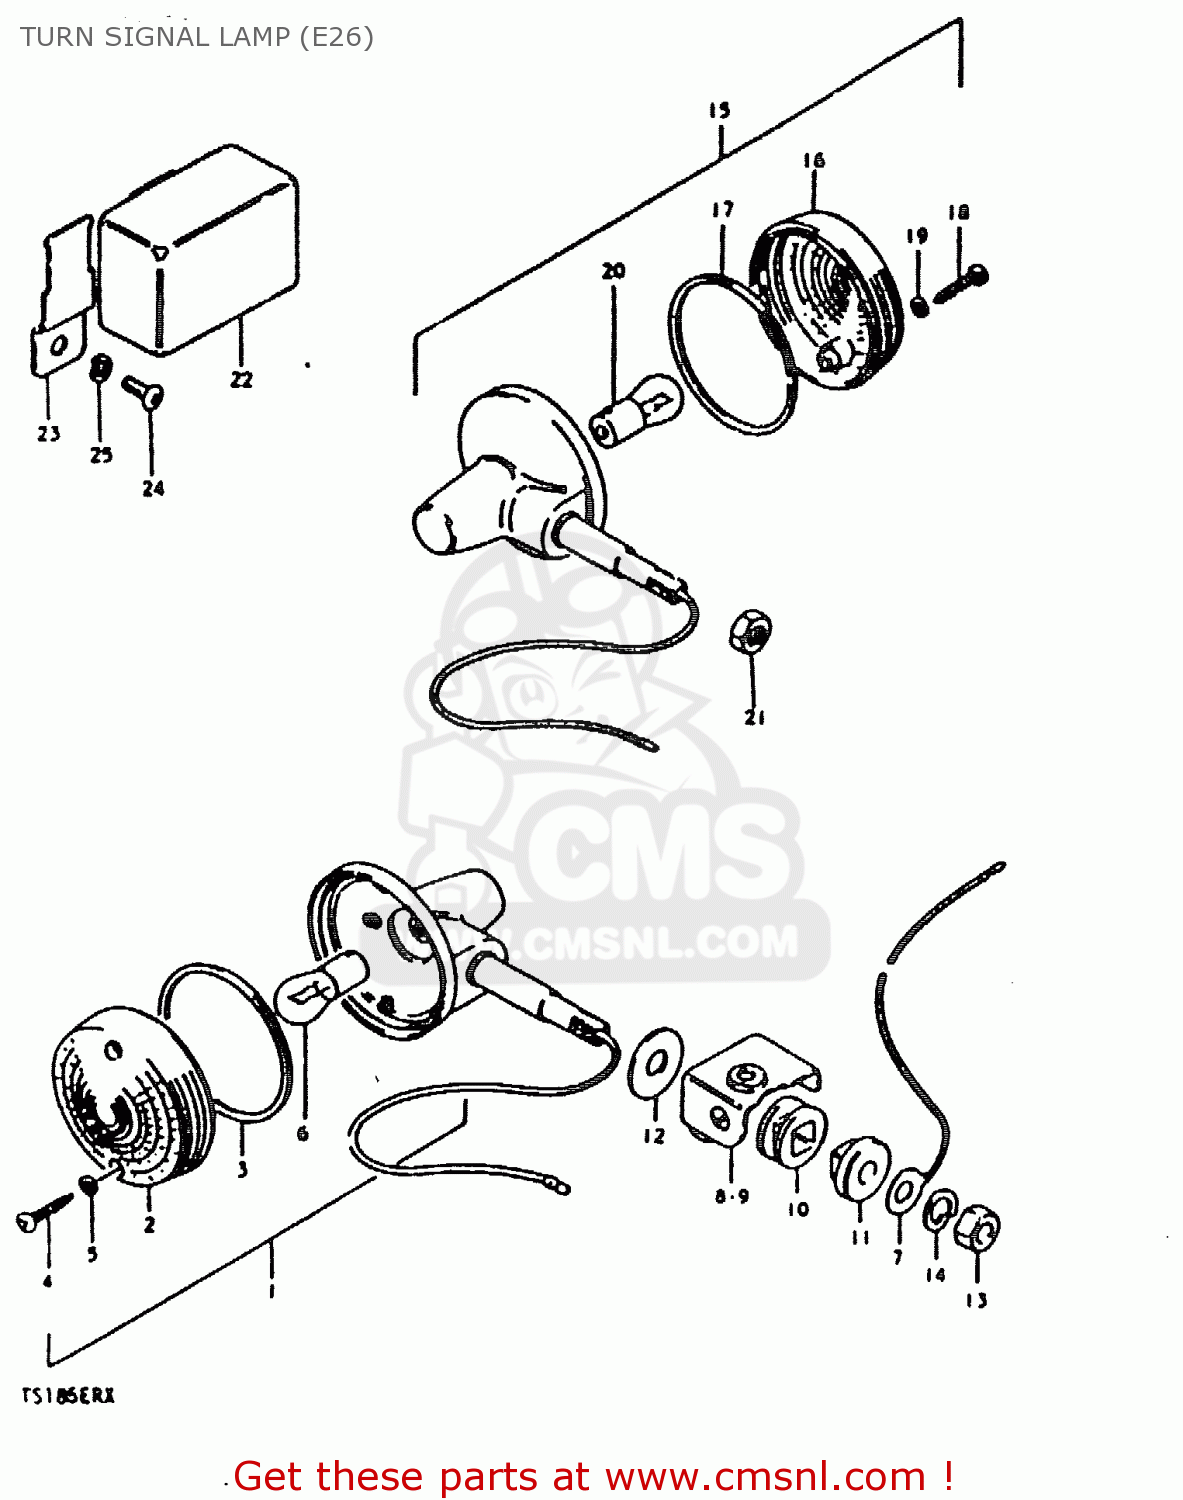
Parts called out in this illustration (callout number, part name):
1	LAMP ASSY,RR TURNSIGNAL
2	LENS
3	GASKET (NAS)
4	SCREW
5	GASKET (NAS)
6	BULB(6V/10W,STANLEY,A4117)
7	LEAD WIRE,EARTH
8	BRACKET,TURNSIGNAL LAMP,R
9	BRACKET,TURNSIGNAL LAMP,L
10	CUSHION
11	SPACER,RR TURNSIGNAL LAMP
12	WASHER (10.5X30X2.3)
13	NUT
14	LOCK WASHER
15	LAMP ASSY,RR TURNSIGNAL
16	LENS
17	GASKET (NAS)
18	SCREW
19	GASKET (NAS)
20	BULB (6V, 10W)
21	NUT
22	RELAY, TURN SIGNAL
23	BRACKET,TURN SIGNAL RELAY
24	SCREW 6X12
25	LOCK WASHER
